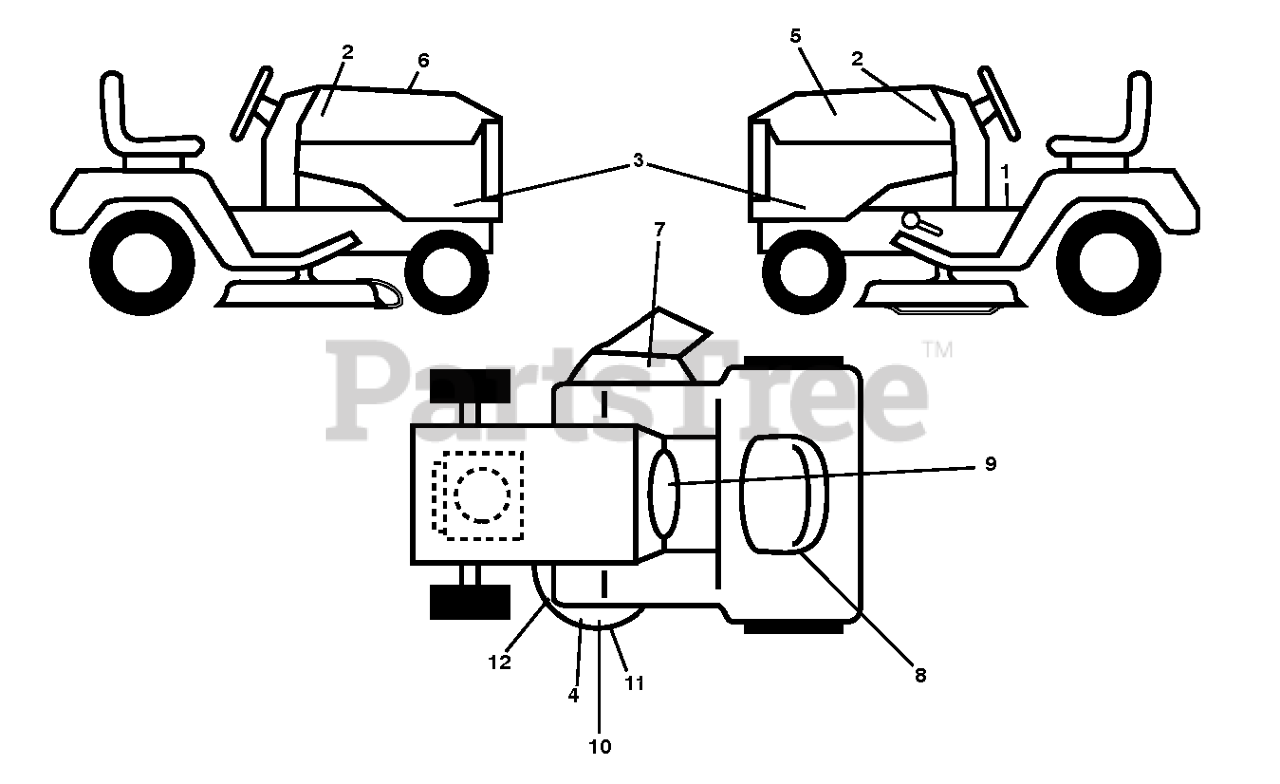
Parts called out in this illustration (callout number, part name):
1	DECAL.FENDER.WARNING.ENGLISH
2	DECAL.BADGE.170MM.TEXTLOGO.
3	DECAL.SDPNL.YT42DXLS.SET
4	DECAL.DECK.CLEARCUT.NOSTEP
5	DECAL.WARNING.CUST.RESP.E85.
6	DECAL.RPL.KOH.KT7.TLB.42F.K46
7	DECAL.TRACT/ZTR.DECKWARN.HUSQ
8	DECAL.RESERVEFUELSELCTR.ENG
9	DECALS.WARN.CA.SPKARREST/PROP
10	DECAL DECK DECAL DECAL.42DECK.
11	DECAL DECK DECAL DECAL.DECK.WA
12	DECAL.V-BELT.SCH.42/46"MEC/ELE
